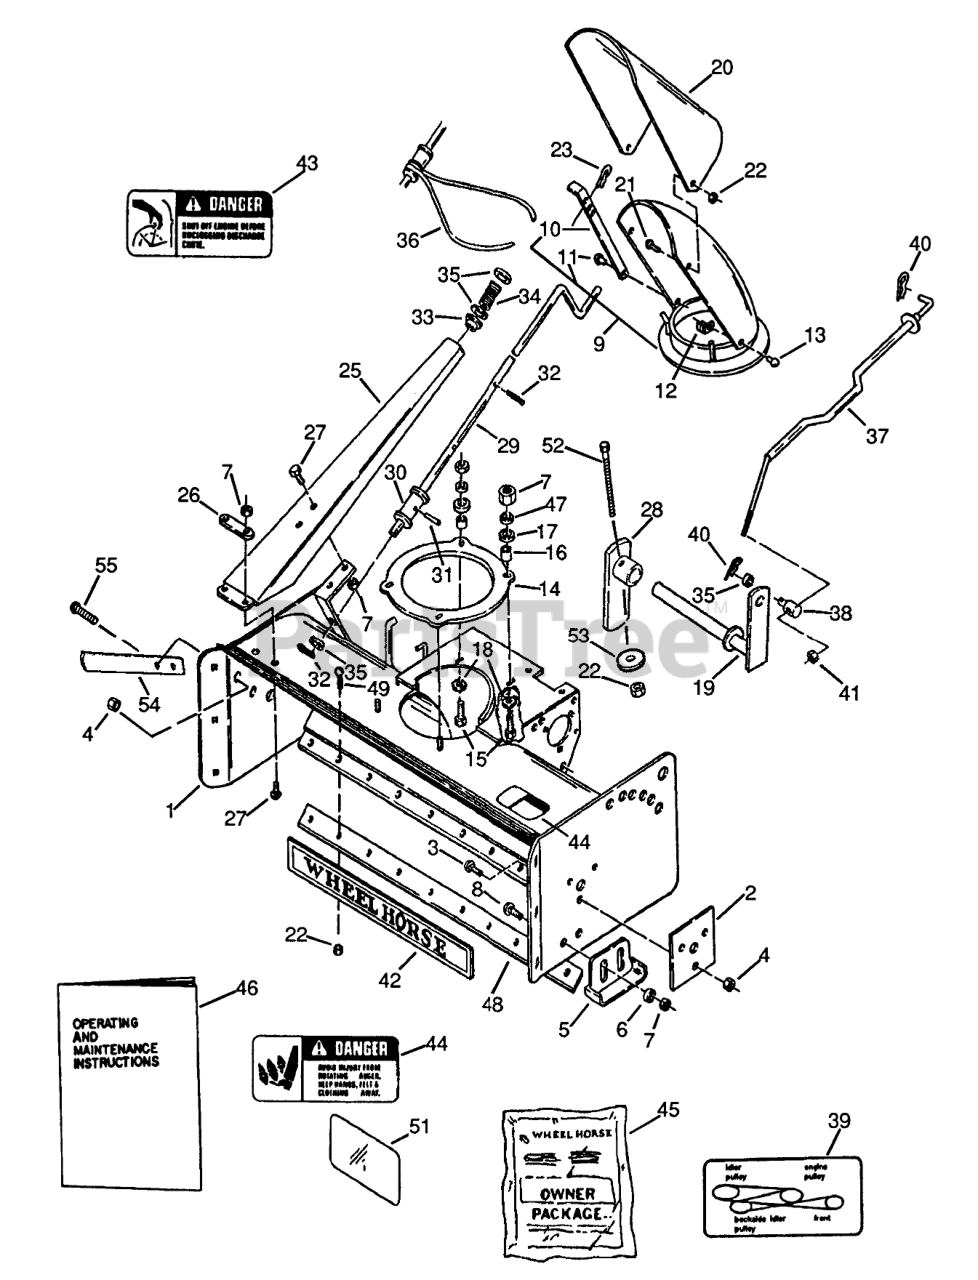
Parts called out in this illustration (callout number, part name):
5	ASS'Y-SKID *R
11	RIVET
12	CLAMP
13	RIVET-4
17	WASHER
23	Hairpin
30	ASSY TUBE CRANK *R
31	ROLL PIN 1/4 X 1-1/4
33	NYLINER BUSHING
34	SPRING-COMPRESSION
36	CABLE
37	LIFT-ROD WLDMT
38	TRUNION
40	Hairpin
46	INSTRUCTION-SHEET
47	WASHER
48	SCRAPER-REVERSIBL *R
51	DECAL-OVERLAY
